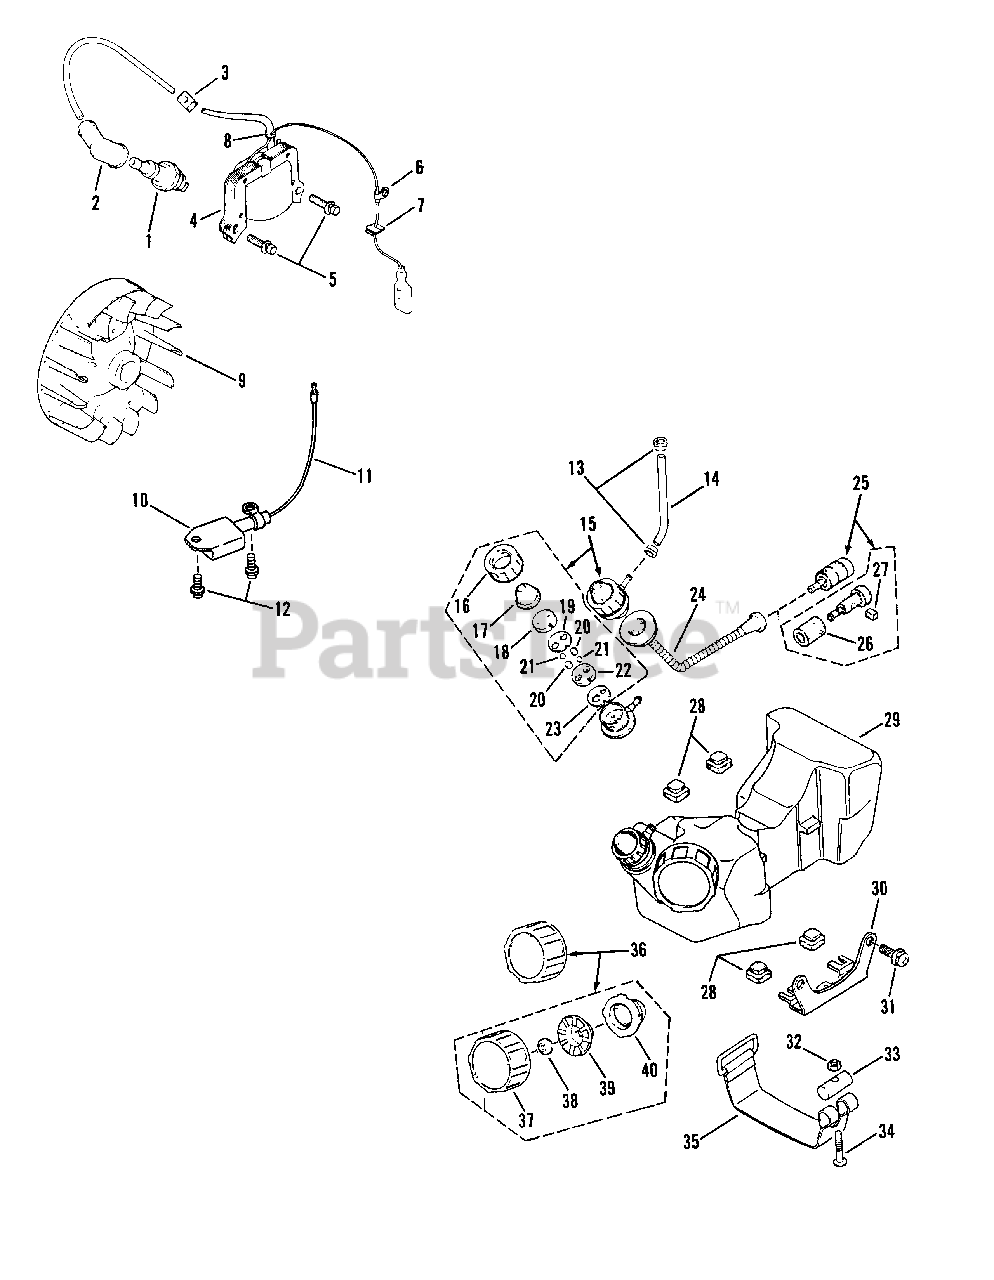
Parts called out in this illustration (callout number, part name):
1	SPARK PLUG (NGK:BM-6A)
2	BOOT, Spark Plug
3	BUSHING, Dust Seal
4	COIL, Ignition
7	BUSHING, Dust Seal
8	BAND
9	FLYWHEEL
10	MTI Unit
11	WIRE, Lead
13	CLIP, Fuel Tube
14	TUBE, Fuel
15	PRIMER PUMP ASSM'Y.
16	CAP, Pump
17	CAP, Rubber
18	SEAT, Valve B
22	SEAT, Valve A
24	HOSE, Fuel
25	FILTER ASSM'Y.,Fuel
29	TANK ASSM'Y.,Fuel
30	HANGER, Tank
31	SCREW, Hanger
33	BAR, Band Support
35	BAND, Tank
36	CAP ASSM'Y.,Fuel
37	CAP, Fuel
40	GASKET
